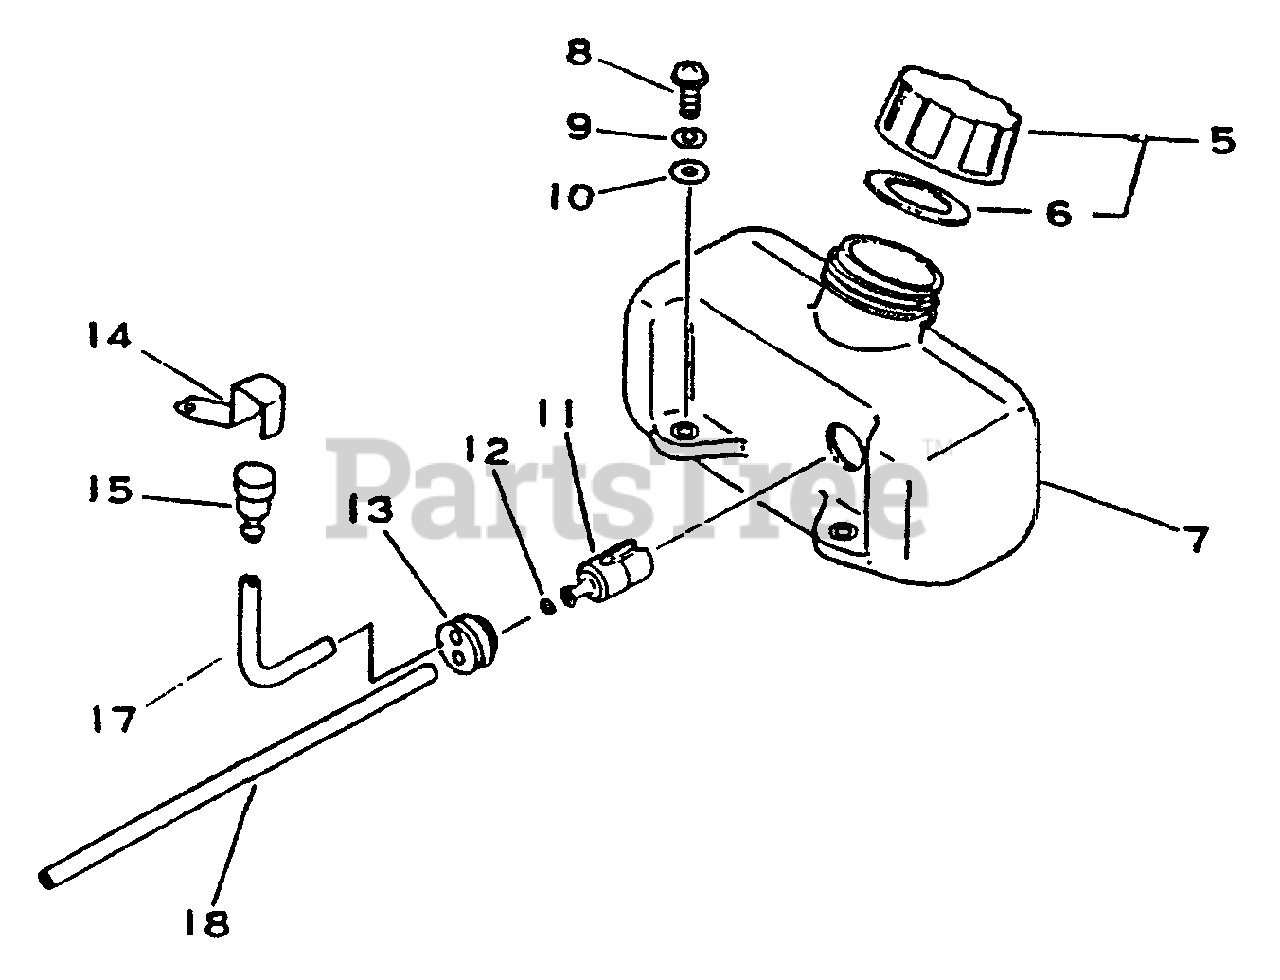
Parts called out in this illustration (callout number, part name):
5	CAP ASSY
6	GASKET, CAP
7	TANK, FUEL
8	SCREW - 5X16
9	LOCKWASHER - 5
10	WASHER - 5
11	FILTER, FUEL
12	CLIP - 6
13	GROMMET
15	VENT, FUEL TANK
17	PIPE - 3X6X70 -- CLEAR
18	PIPE - 3X5X180 -- BLACK
